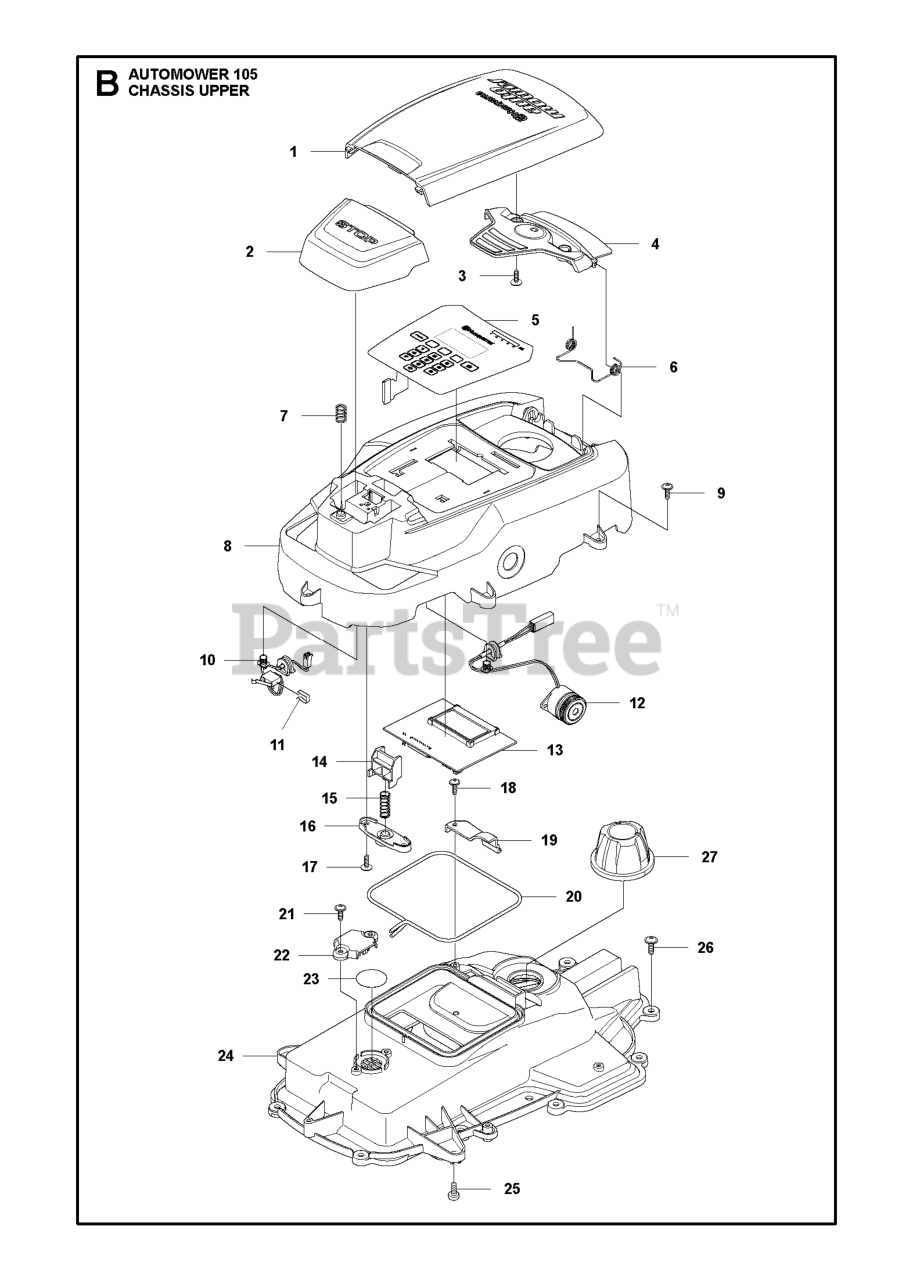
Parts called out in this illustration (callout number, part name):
3	SCREW 14MM
7	SPRING STOP BUTTON
9	SCREW 14MM
10	SWITCH STOP BUTTON
11	CLIP RETAINER
12	BUZZER DISPLAY COVER
13	PRINTED CIRCUIT ASSY MMI BOARD
14	LOCK STOP BUTTON
15	SPRING LOCK STOP BUTTON
16	SPRING HOLDER STOP BUTTON
17	SCREW 14MM
18	SCREW 14MM
19	COVER HEIGHT INDICATOR
20	SEALING STRIP P1
21	SCREW 14MM
22	COVER AIR FILTER
23	KIT AIR FILTER KIT 305 - 10 PC
24	KIT CHASSIS UPPER KIT INCL. SE
25	SCREW ISO 14583 M5X12 T25 A2-7
26	SCREW ITXPANT
